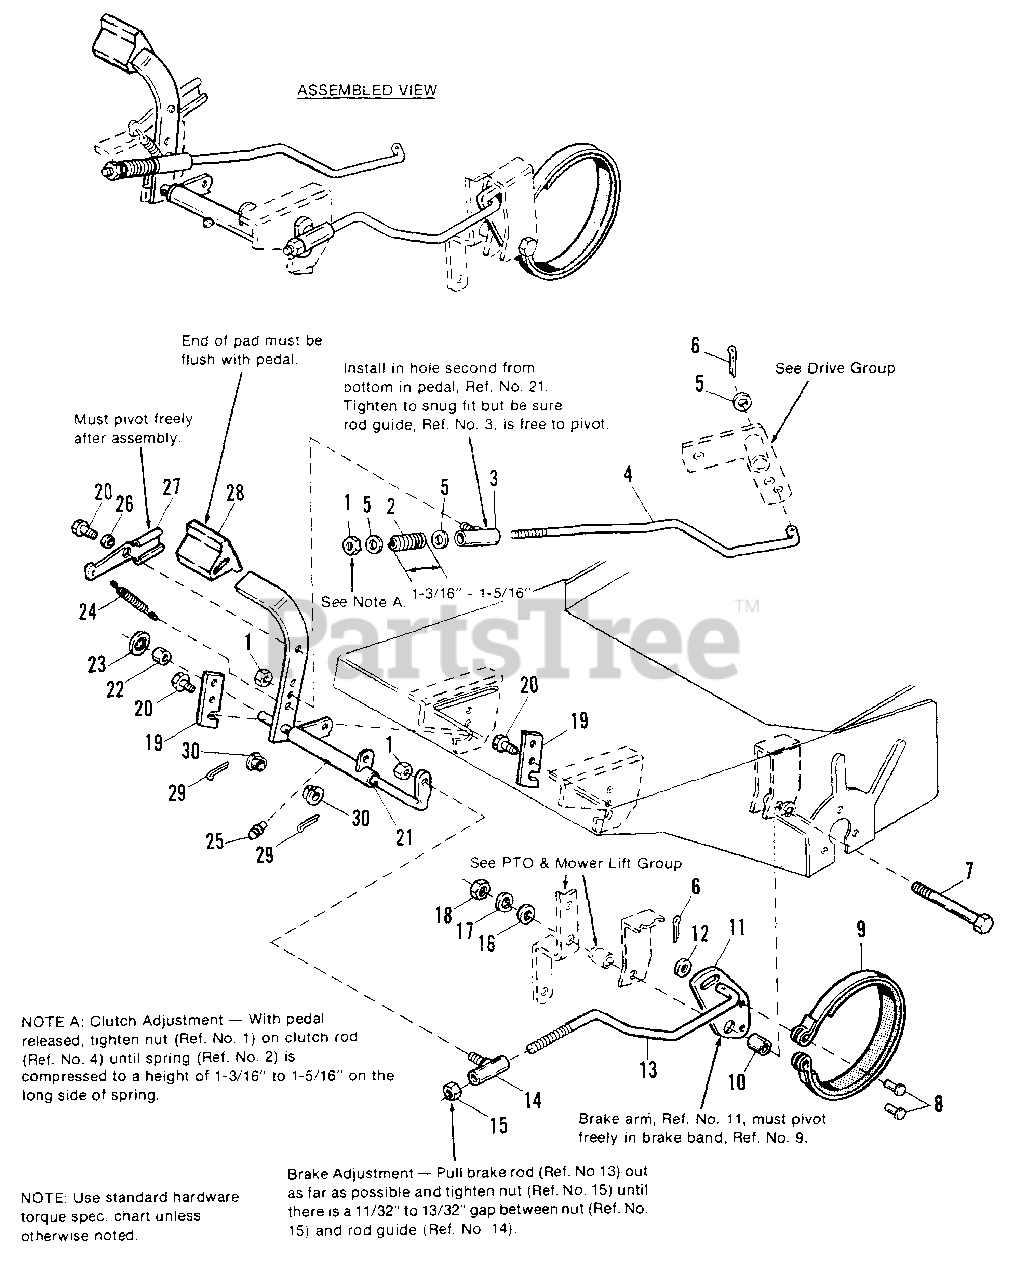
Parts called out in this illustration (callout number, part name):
1	NUT, Hex Lock, 5/16-18
3	GUIDE ASSY., Rod
4	ROD, Clutch
5	WASHER, 5/16
6	PIN, Cotter, 3/4
7	CAPSCREW, 1/2-13 x 3-1/2, Gr. 5
9	BAND ASSY., Brake
11	LINK, Brake Arm
12	WASHER, 3/8
13	ROD, Brake
14	GUIDE ASSY., Rod
15	NUT, Hex Lock, 3/8-16
16	WASHER, 1/2
17	LOCKWASHER, 1/2
18	NUT, Hex, 1/2-13
19	BRACKET, Brake
20	SCREW, Taptite, 5/16-18 x 1/2
21	SHAFT ASSY., Brake
25	FITTING, Grease
27	LATCH, Brake
29	PIN, Cotter, 3/4
30	BUSHING, Nylon, Split
